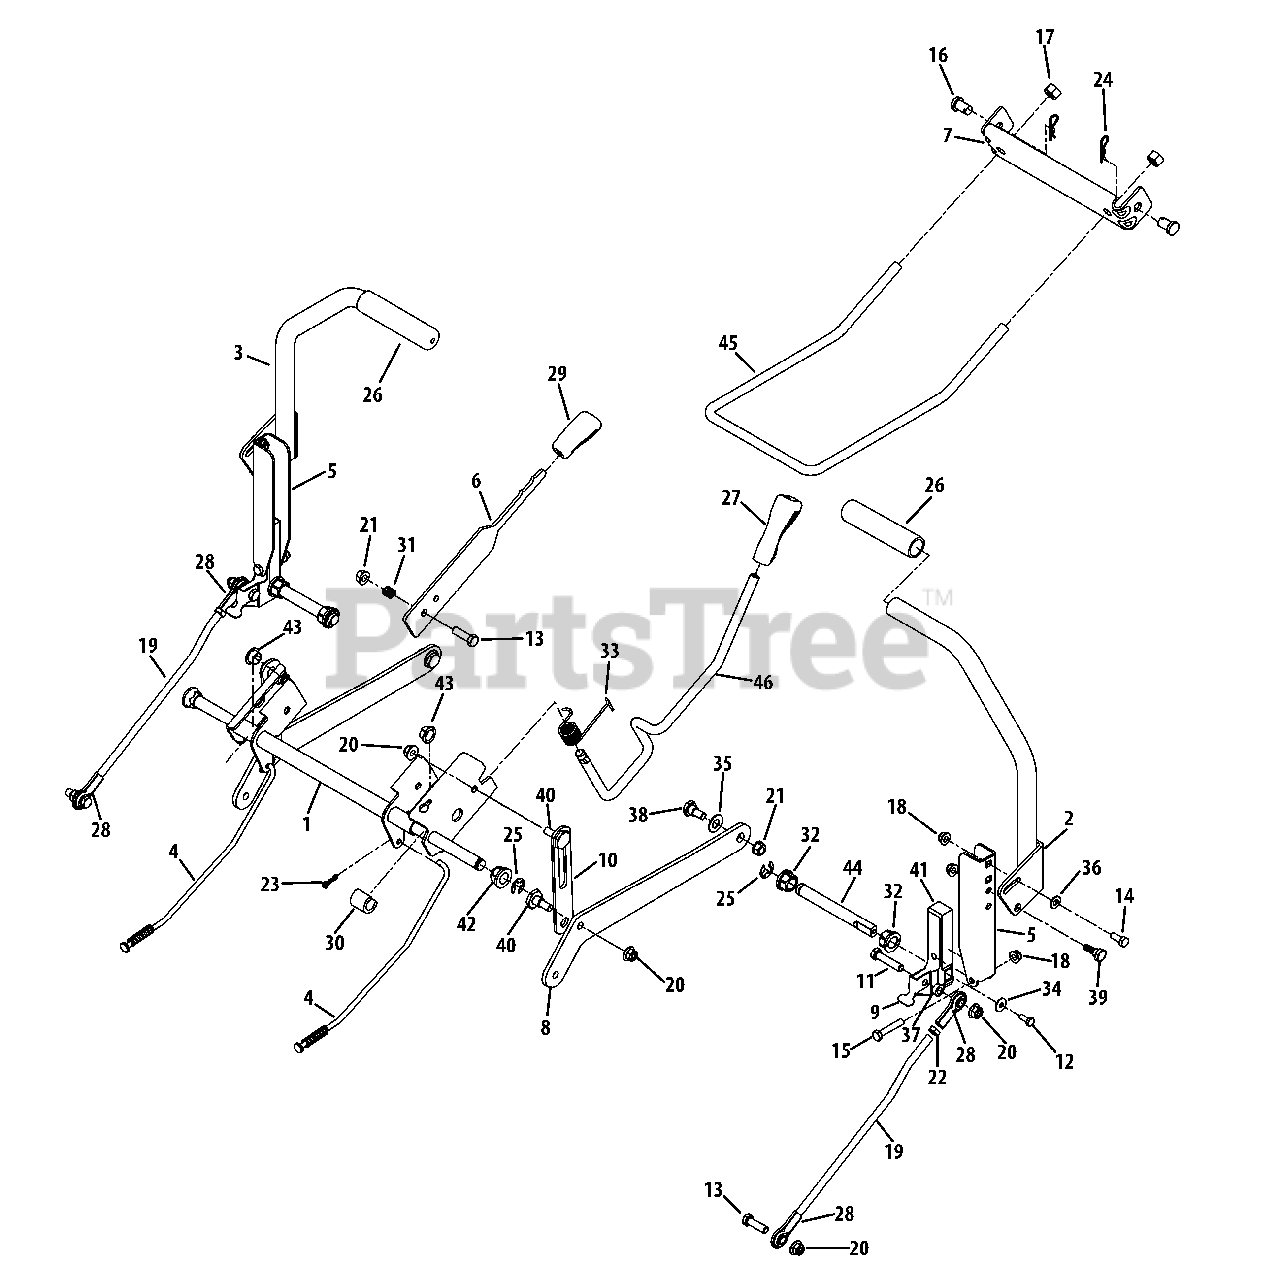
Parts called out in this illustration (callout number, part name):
1	Deck Lift Shift Assembly
2	RH Lapbar Lever Assembly
3	LH Labpar Lever Assembly
4	Brake Rod Assembly
5	Lapbar Pivot Bracket
6	Brake/Shabs Assembly
7	Front Deck Hanger Bracket
8	Deck Lift Arm Plate
9	Switch Actuator Bracket
10	Lift Link Plate
11	Hex Screw, 3/8-16 x 1.75
12	Hex Screw, 1/4-20 x .625
13	Hex Screw, 3/8-16 x 1.25
14	Hex Screw, 5/16-18 x .75
15	Hex Screw, 5/16-18 x 1.75
16	Clevis Pin, .50 x .78
17	Flex Lock Nut, 1/2-13
18	Flange Lock Nut, 5/16-18
19	Lapbar Control Rod
20	Flange Lock Nut, 3/8-16
21	Hex Lock Nut, 3/8-16, Centerlock
22	Jam Nut, 3/8
23	Bow-Tie Cotter Pin
24	Cotter Pin, .080 x 1.5625
25	E-Ring
26	Lapbar Grip
27	Handle Grip, 1/2
28	Rod End
29	Selector Handle
30	Spacer, .621 x 1.00
31	Compression Spring, .50 x .50
32	Hex Flange Bearing, .629
33	Torsion Spring
34	Bell Washer, .265 x .75 x .062
35	Flat Washer, .510 x 1.00 x .060
36	Flat Washer, .344 x .688 x .065
37	Spacer, .380 x .625 x .265
38	Shoulder Bolt, 3/8-16 x .496 x .336
39	Shoulder Screw, 5/16 x .437 x .268
40	Shoulder Screw, .500 x .434
41	Control Hub
42	Hex Flange Bearing
43	Flange Bearing, .626 x .938 x .344
44	Shaft Control
45	Front Hanger Deck Lift Rod
46	Deck Lift Handle Rod
